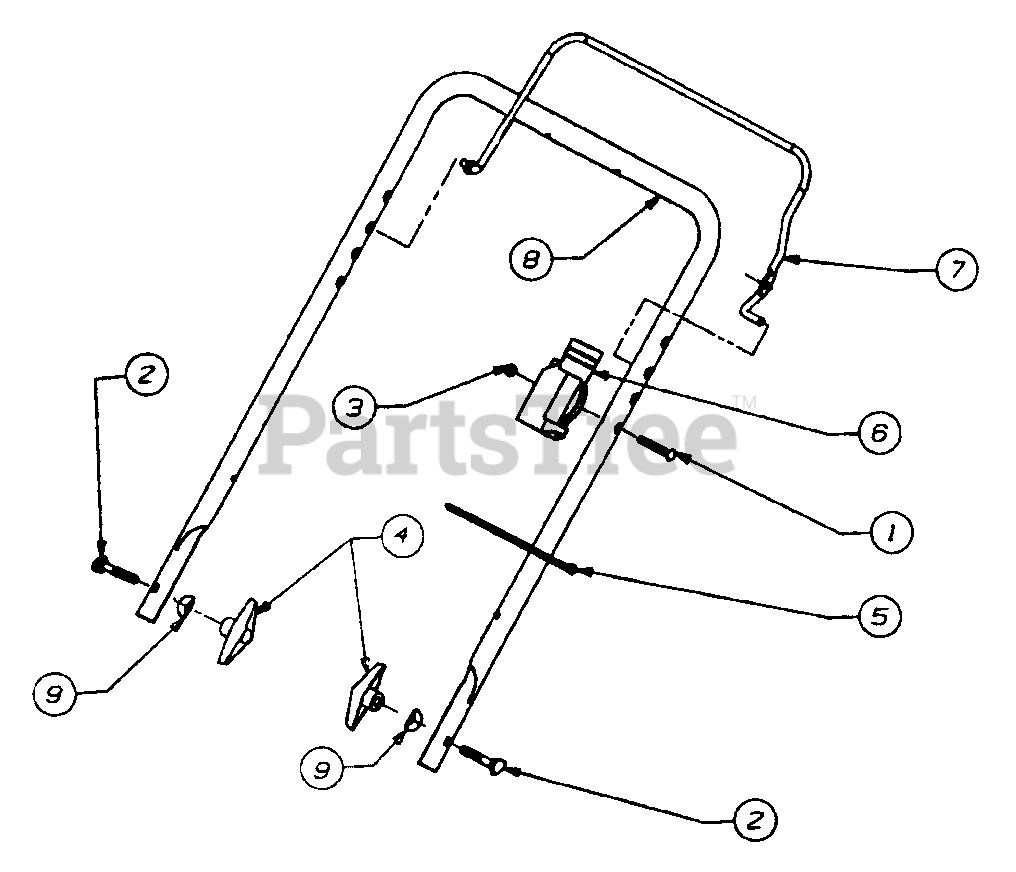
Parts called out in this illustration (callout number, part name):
1	Oval C-Sunk Screw
2	Carriage Bolt
3	Lock Nut
4	Handle Knob
5	Cable Tie
6	Control Lever
